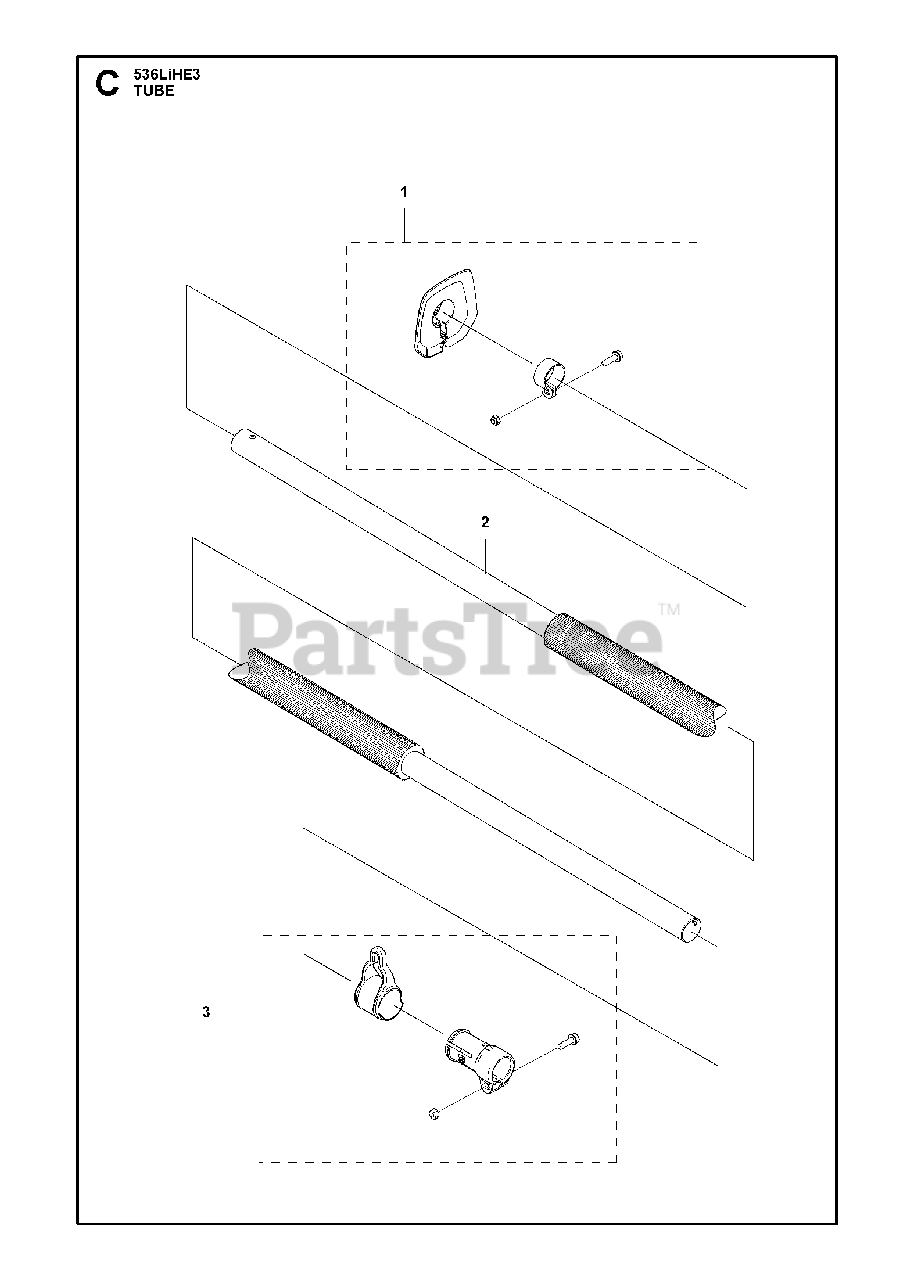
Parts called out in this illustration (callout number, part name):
1	HANDGUARD ASSY
2	TUBE ASSY POLE H
3	CORD BRACKET CPL BATTERY POLE
